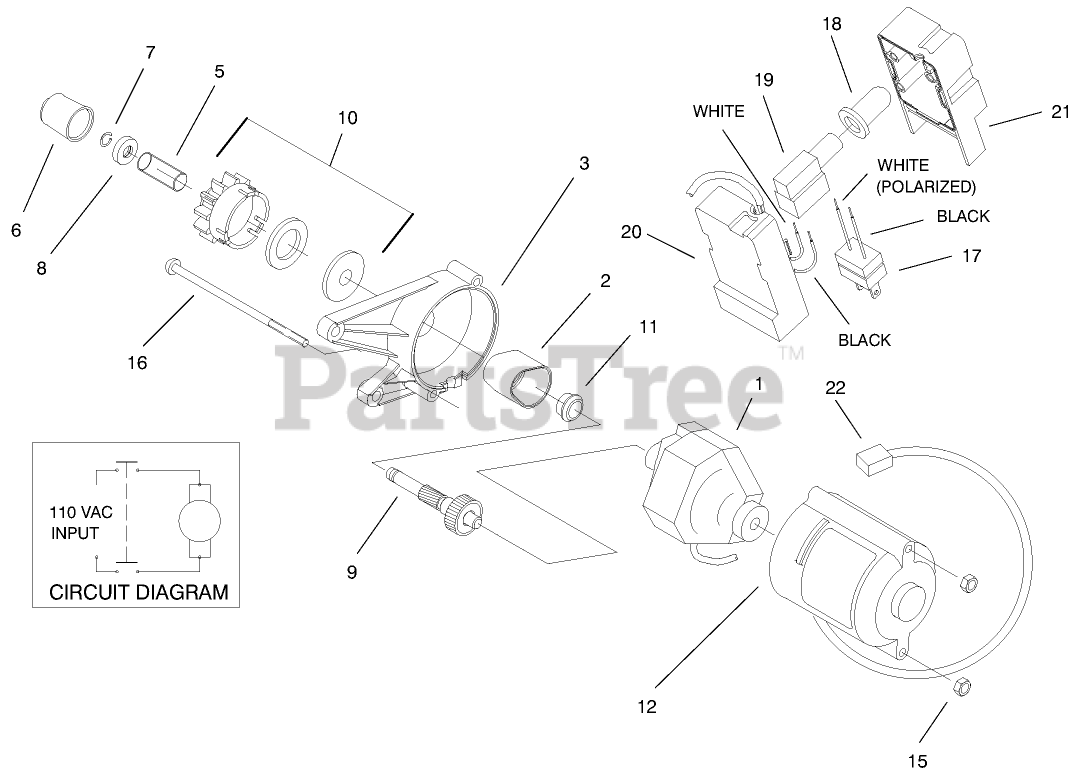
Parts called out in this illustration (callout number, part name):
2	COVER-GEAR
5	SPRING
6	CAP-PINION
7	RING-LOCK
8	PINION STOP
10	PINION ASM
11	BUSHING
15	NUT-LOCK, NI
17	PLUG-POWER
18	BOOT-SWITCH
19	SWITCH-STARTER
20	LEVER - ADJUSTING
21	PLATE - COVER
22	TIE-CABLE
